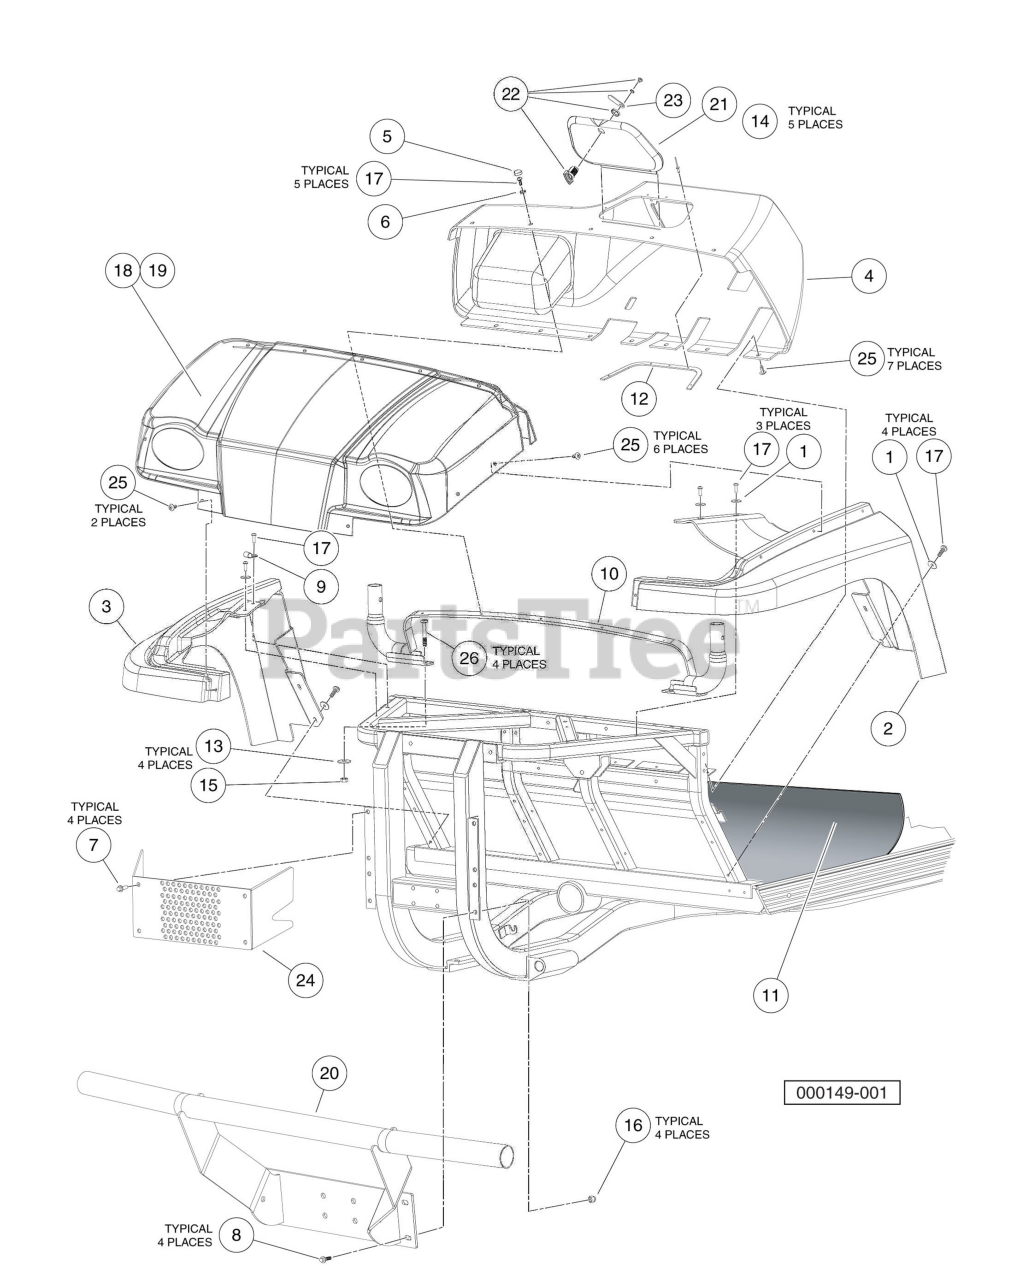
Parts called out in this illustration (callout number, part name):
1	Washer, 1/4" Type B Flat
2	Fender, Left Front
3	Fender, Right Front
4	Dashboard with Access Hole
5	Cap, 1/4" Plastic Screw Head
6	Washer, 1/4 Id Scalloped Plast
7	Screw, M8 X 1.25 X 30 Tri, Blk
8	Bolt, Flange Head, M8 X 30.0
9	P-Clamp, Insulated .312 In
10	Weldment, Support, ROPS
11	Mat, Floor
12	Support, Access Panel, Dash
13	Washer Hard,m10.
14	Rivet, .125" Dia, .311" Panel
15	Nut Flg M10 X 1.5 Mech Def
16	Lock Nut, Flg M8 X 1.25 Nylon
17	Screw, 1/4-20 X 1.0 Pn Hd Torx
18	Cowl, Camo
19	Cowl, Orange
20	Brush Guard
21	Panel, Access, Dash
22	Cam Lock Body
23	Latch, Cam, Access Panel
24	Guard, Radiator
25	Rivet, Removable, Tuflok 1/4"
26	Bolt, M10 X 1.50 X 65
